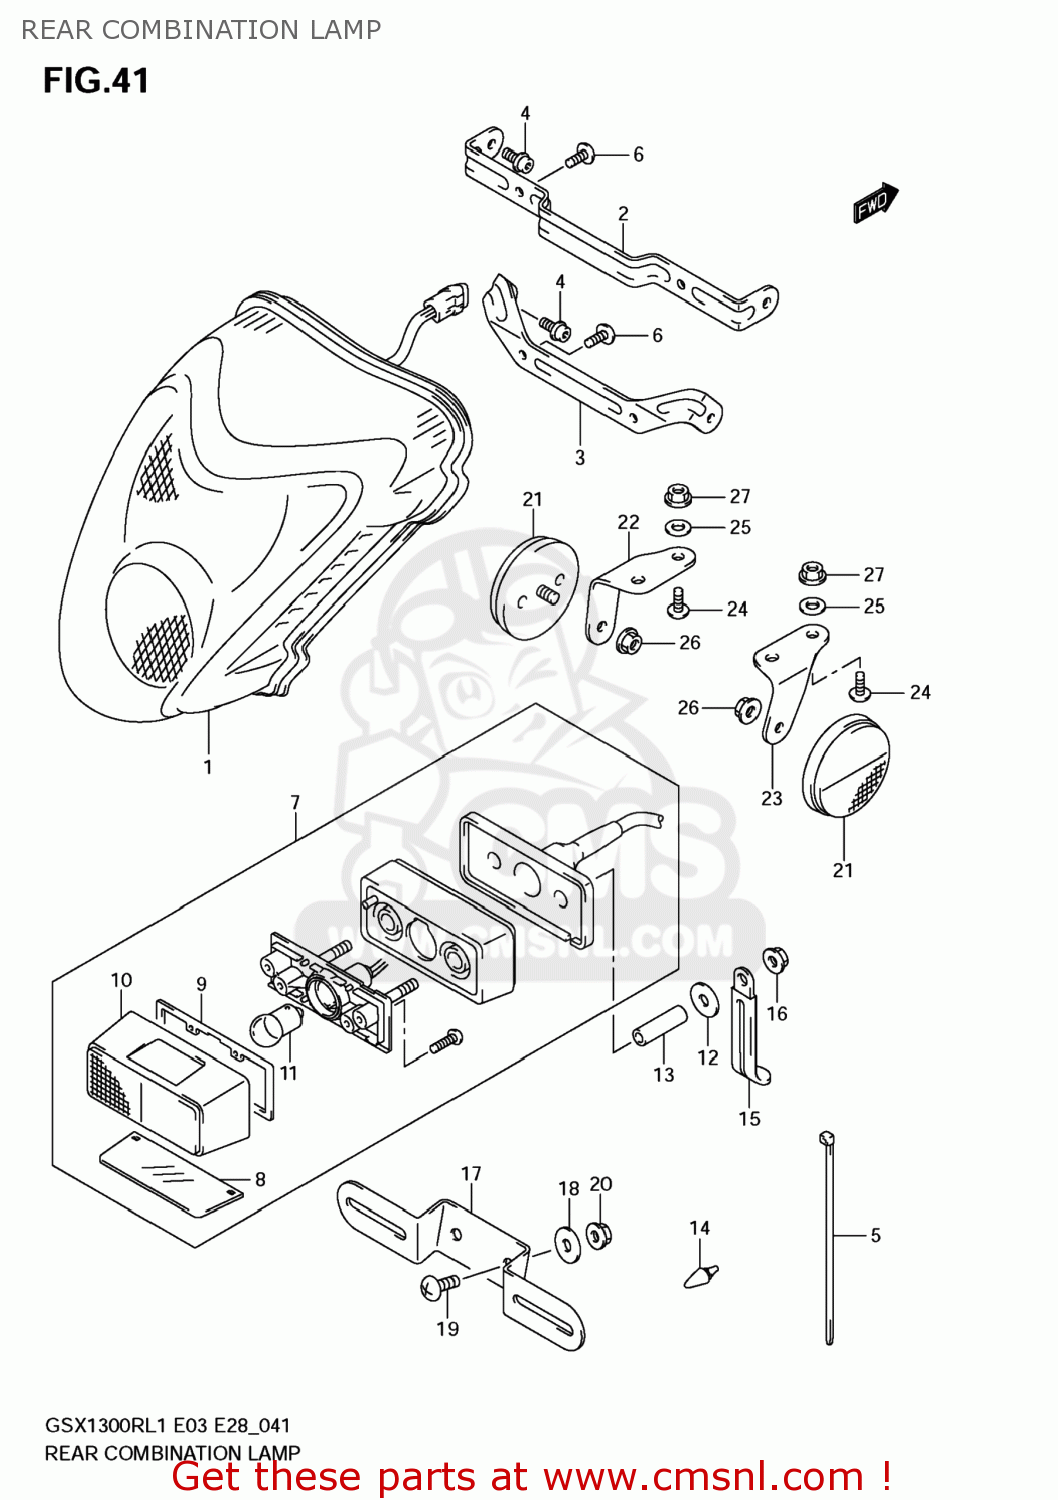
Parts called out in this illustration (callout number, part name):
1	LAMP ASSY,RR COMBINATION
2	BRACKET,RR COMBINATION LAMP
3	BRACKET,RR COMBINATION LAMP
4	BOLT(5X12)
5	CLAMP(L:145)
6	SCREW
7	LAMP ASSY,LICE
8	LENS LICENCE
9	GASKET (NAS)
10	COVER,LICENSE LAMP
11	BULB(12V5W,BF150-40160A)
12	WASHER(6.5X20X1.2)
13	SPACER(6.5X9X34)
14	CUSHION
15	CLAMP(L:45)
16	NUT
17	BRACKET,LICENSE PLATE
18	WASHER(6.5X20X1.2)
19	SCREW
20	NUT
21	REFLECTOR ASSY,RR SIDE
22	BRACKET,RR SIDE RR,R
23	BRACKET,RR SIDE RR,L
24	SCREW
25	WASHER(6.5X14X2)
26	NUT
27	NUT
